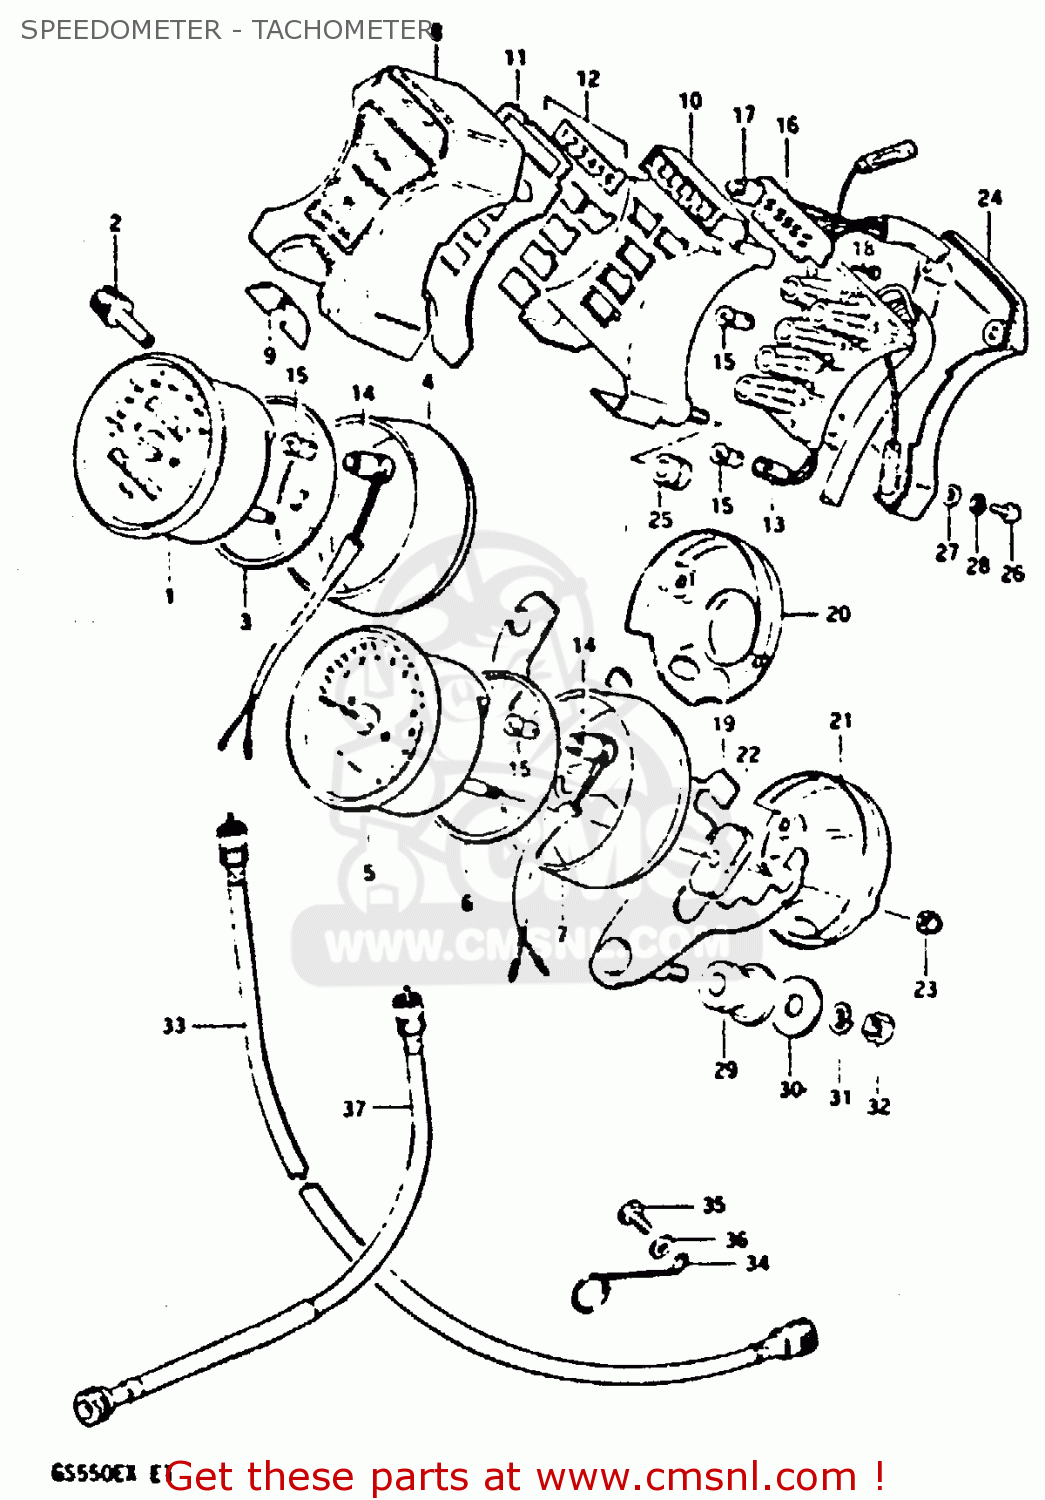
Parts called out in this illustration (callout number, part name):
1	SPEEDOMETER
2	KNOB,TRIP
3	CUSHION,SPEEDOMETER
4	COVER,SPEEDOMETER
5	TACHOMETER
6	CUSHION,SPEEDOMETER
7	COVER,TACHOMETER
8	CASE,PILOT BULB
9	PAD
10	CASE,PILOT BULB,INNER
11	PLATE,PILOT BOX
12	LENS SET,PILOT LAMP
13	SOCKET
14	SOCKET,METER
15	BULB(12V3.4W,STANLEY,A72A)
16	SOCKET,GEAR INDICATOR
17	BULB(14V1.12W)
18	SCREW,GEAR INDICATOR
19	BRACKET,COMBINATION METER
20	COVER,SPEEDOMETER,UNDER
21	COVER,TACHOMETER,UNDER
22	CUSHION,METER
23	NUT
24	COVER,PILOT BOX,UNDER
25	CUSHION
26	SCREW
27	WASHER
28	LOCK WASHER
29	CUSHION,METER BRACKET
30	WASHER (8.5X29X1.6)
31	LOCK WASHER
32	NUT
33	CABLE ASSEMBLY,SPEEDOMETER
34	CLAMP,SPEEDOMETER CABLE
35	BOLT, UPPER
36	WASHER
37	CABLE ASSEMBLY,TACHOMETER
